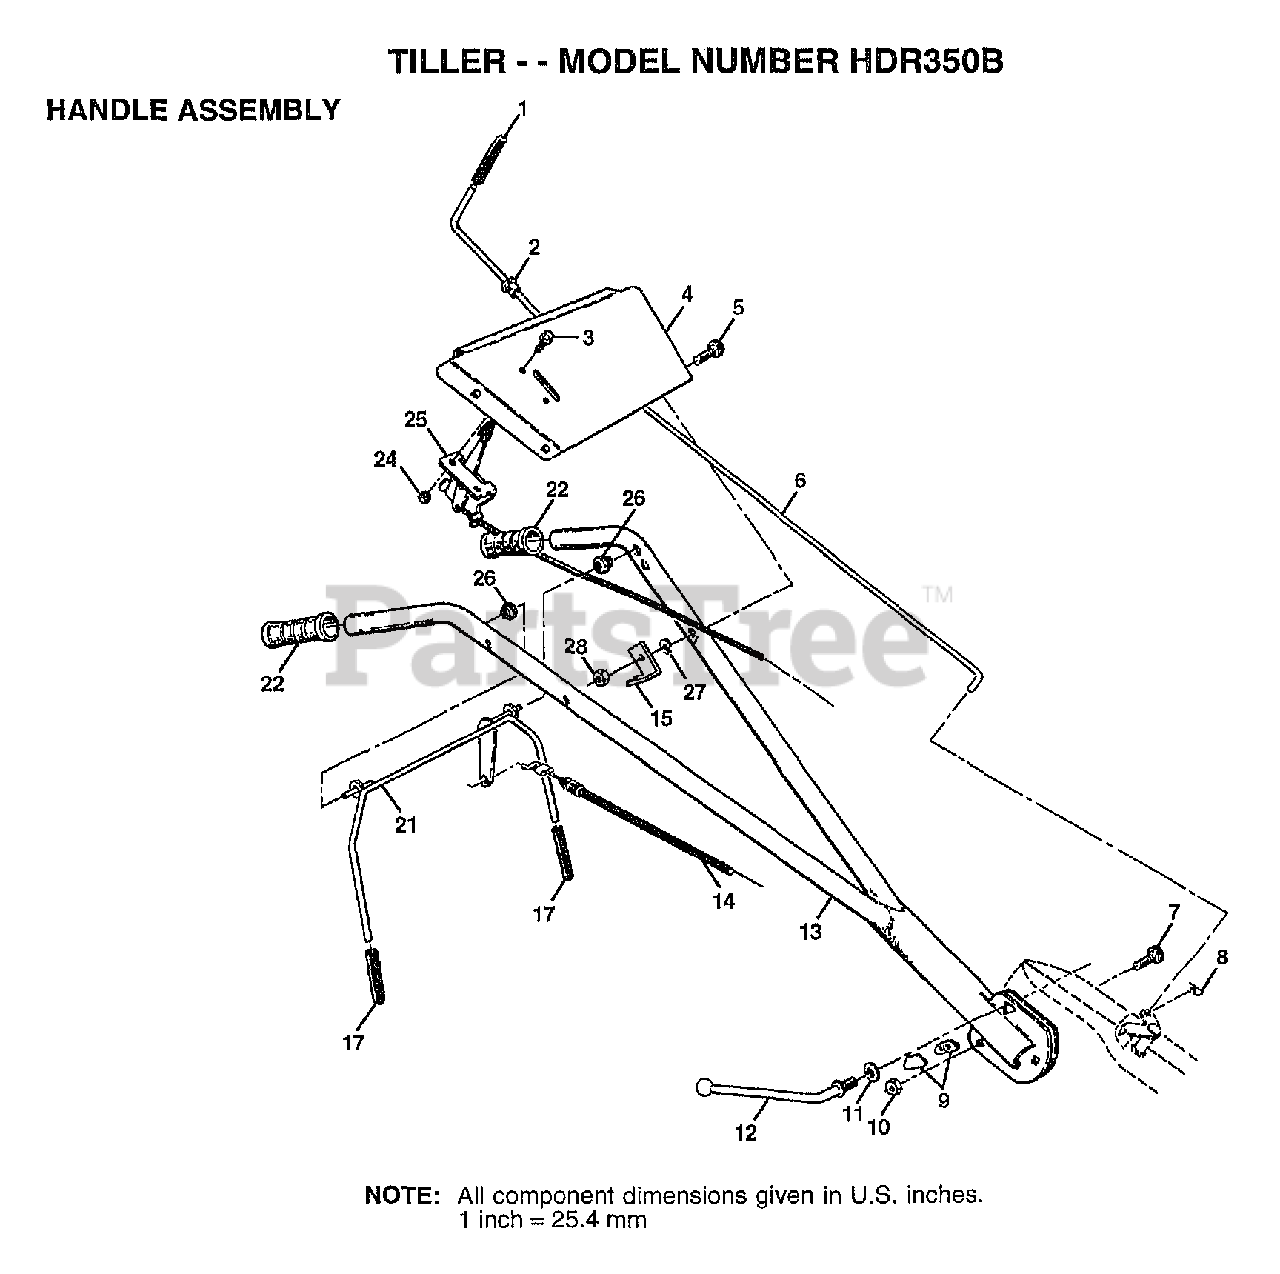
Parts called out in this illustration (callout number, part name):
1	GRIP TI
2	BUSHING
3	SCREW.PNHD.10-24
4	BRACKET.HDLE.TILL
5	BOLT CARRIAGE CRT
6	ROD SHIFT CRT
7	BOLT D
8	RETAINER M
9	LOCK CRT
10	LOCKNUT
11	WASHER CRT
12	LEVER LOCK CRT
13	HANDLE.ASM.V-PLOW
14	CABLE.CLUTCH.Z-BE
15	BRACKET.CLUTCH.CA
17	GRIP BAR CRT
21	BAR.ASM.CNTRL.VPL
22	GRIP HDLE NUBBED
25	"CONT,THROTTLE"
26	GROMMET.HANDLE.V-
27	LOCKWASHER
28	NUT
